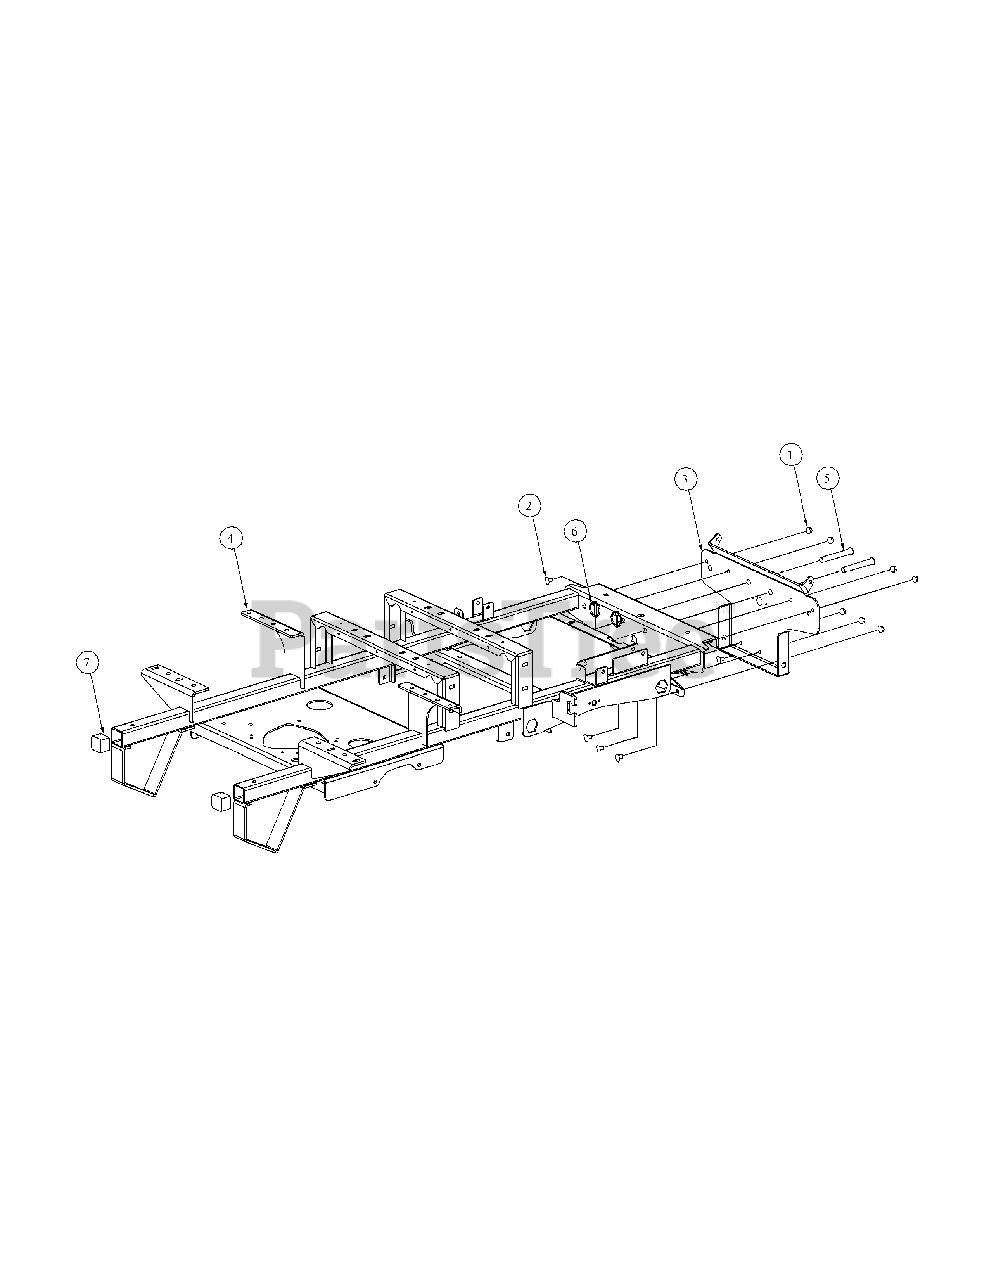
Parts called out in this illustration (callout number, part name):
1	Hex Nut, 3/8-16 Flange Lock
2	Carriage Bolt, 3/8-16 x .75 Long
3	Bracket Assembly, Frame, Front
4	Frame Assembly
5	Clevis Pin, .500 Dia x 4.375 Long
6	Linch Pin, 3/16 Dia.
7	Plug, Square Tube
